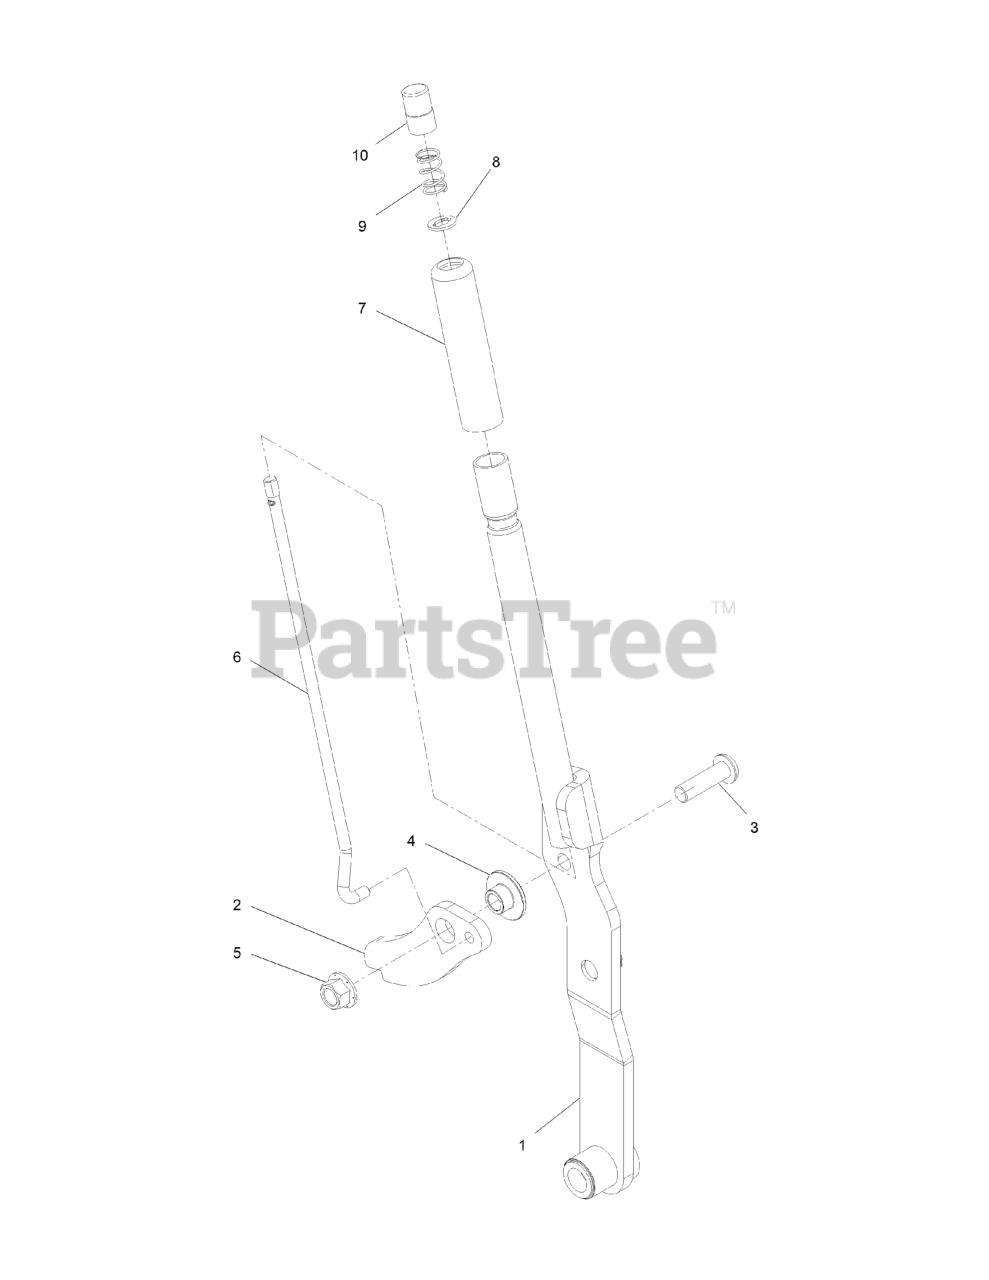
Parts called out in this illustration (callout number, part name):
1	ASM, HOC LEVER W/ BUSHINGS
2	ARM, TRANSPORT LOCK
3	SCREW-HSBH
5	Nut-Lock 1/2-13
6	LINC, HOC
8	WASHER-SPECIAL
9	SPRING-COMPRESSION
10	BUTTON, PUSH
